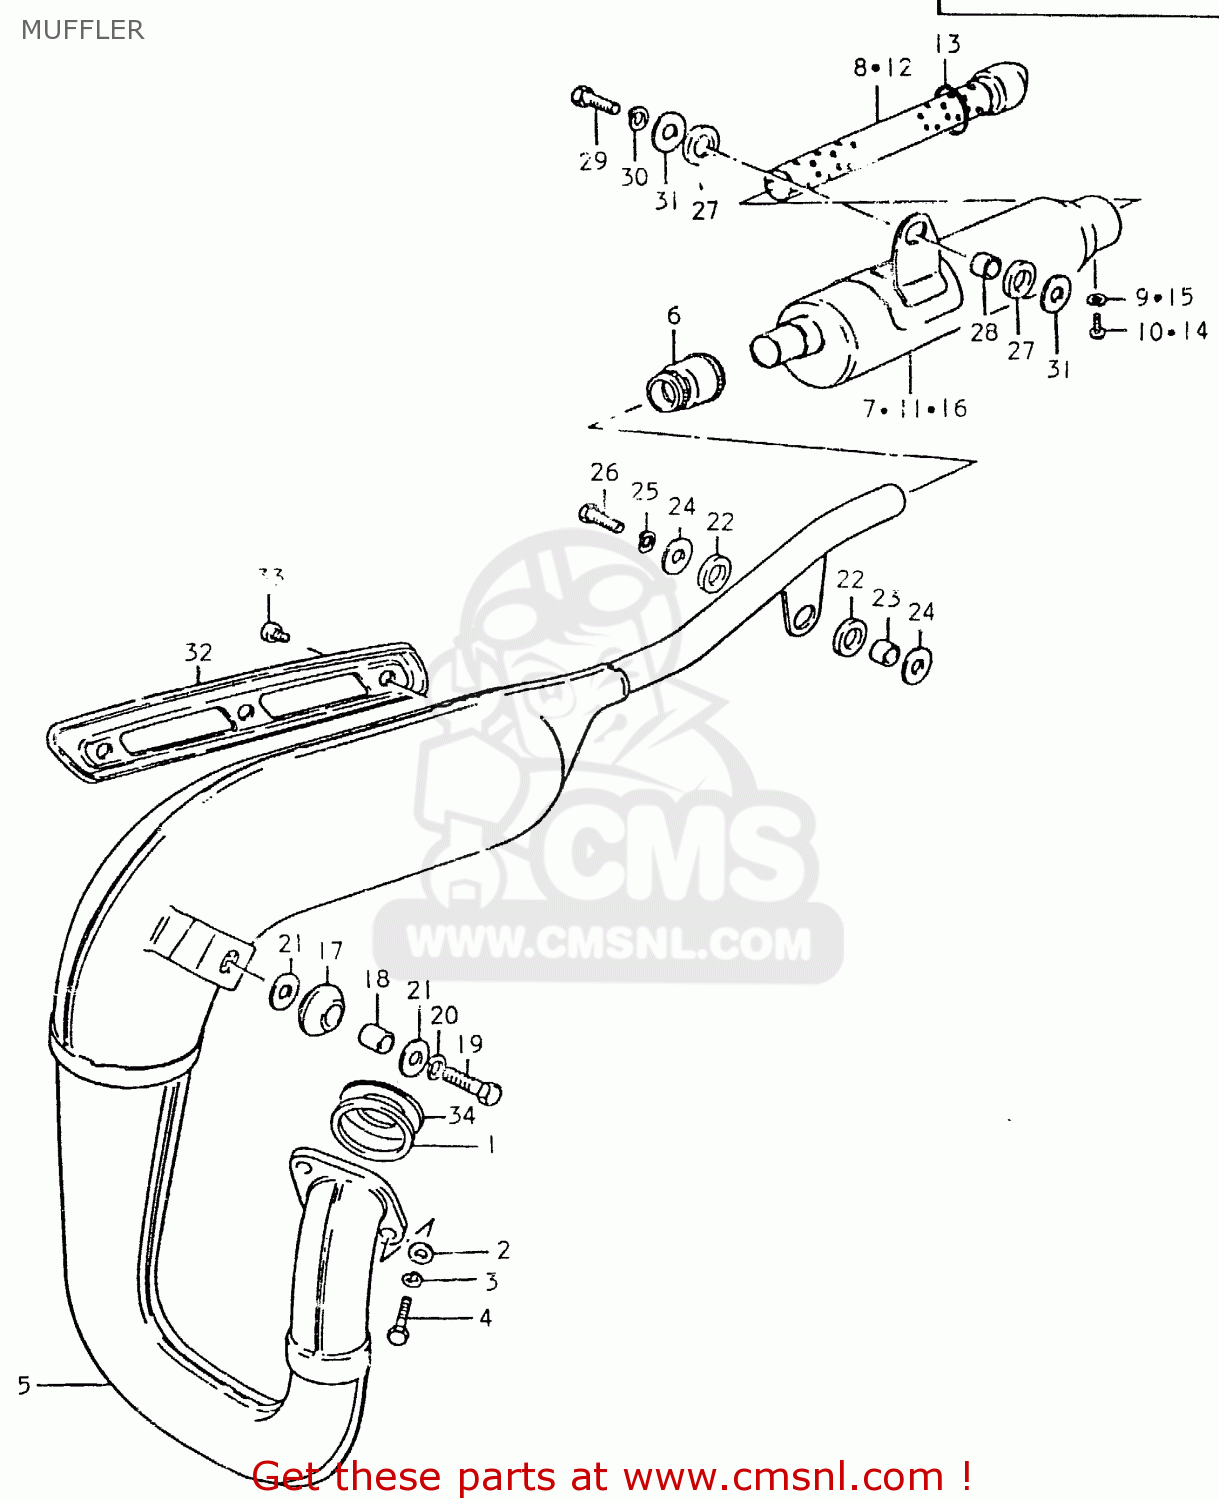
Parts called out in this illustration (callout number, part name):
1	GASKET,EXHAUST PIPE (NAS)
2	WASHER
3	LOCK WASHER
4	SCREW (6X25)
5	BODY,MUFFLER
6	CONNECTOR,MUFFLER
7	MUFFLER ASSY,2ND
8	PIPE,BAFFLE
9	LOCK WASHER
10	SCREW
11	MUFFLER ASSY, 2ND
12	PIPE, BUFFLE
13	O RING
14	SCREW
15	LOCK WASHER
16	MUFFLER ASSY, 2ND (NON-RENOVEABLE TYPE)
17	DAMPER,MUFFLER,FR
18	SPACER (8X12X15)
19	BOLT
20	LOCK WASHER
21	WASHER (8.7X22X2)
22	CUSHION
23	SPACER (8.6X13.8X9.8)
24	WASHER
25	LOCK WASHER
26	BOLT
27	CUSHION
28	SPACER (8.6X13.8X9)
29	BOLT
30	LOCK WASHER
31	WASHER
32	COVER,MUFFLER
33	SCREW
34	PLATE, EXHAUST PIPE
